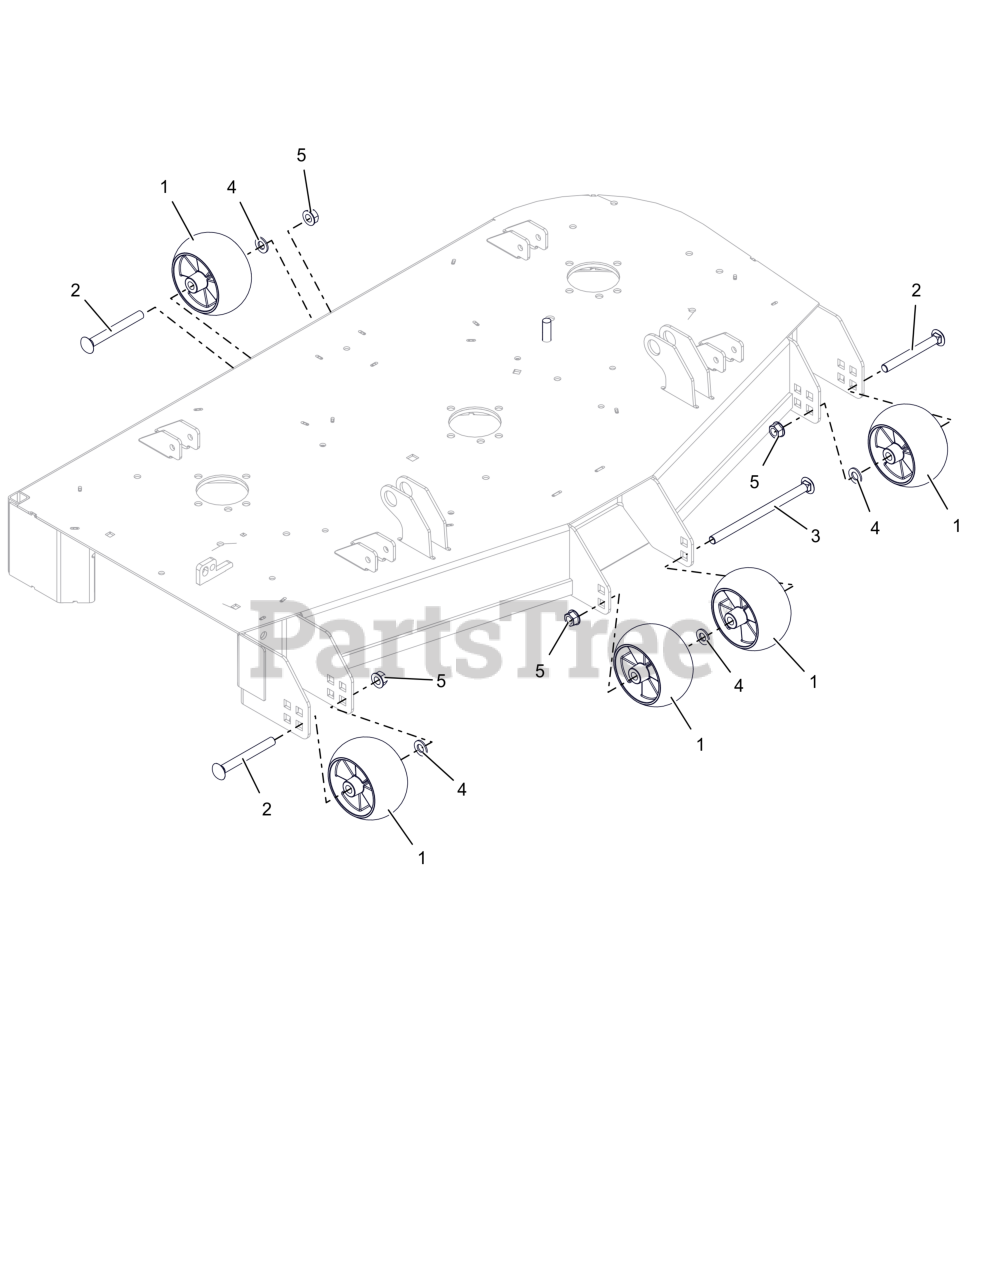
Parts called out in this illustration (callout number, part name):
1	WHEEL, ANTI SCALP - 5X3 CTR W/RIBS
2	BOLT, RHNS .50-13X4.50 G5 ZCC NS
3	BOLT, RHNS .50-13X8.00 G5 ZCC NS
4	WSHR,WAVE- TPE .525 X 1.00 X .090
5	NUT-LK-CTR-FLG .500-13 GG ZCC
